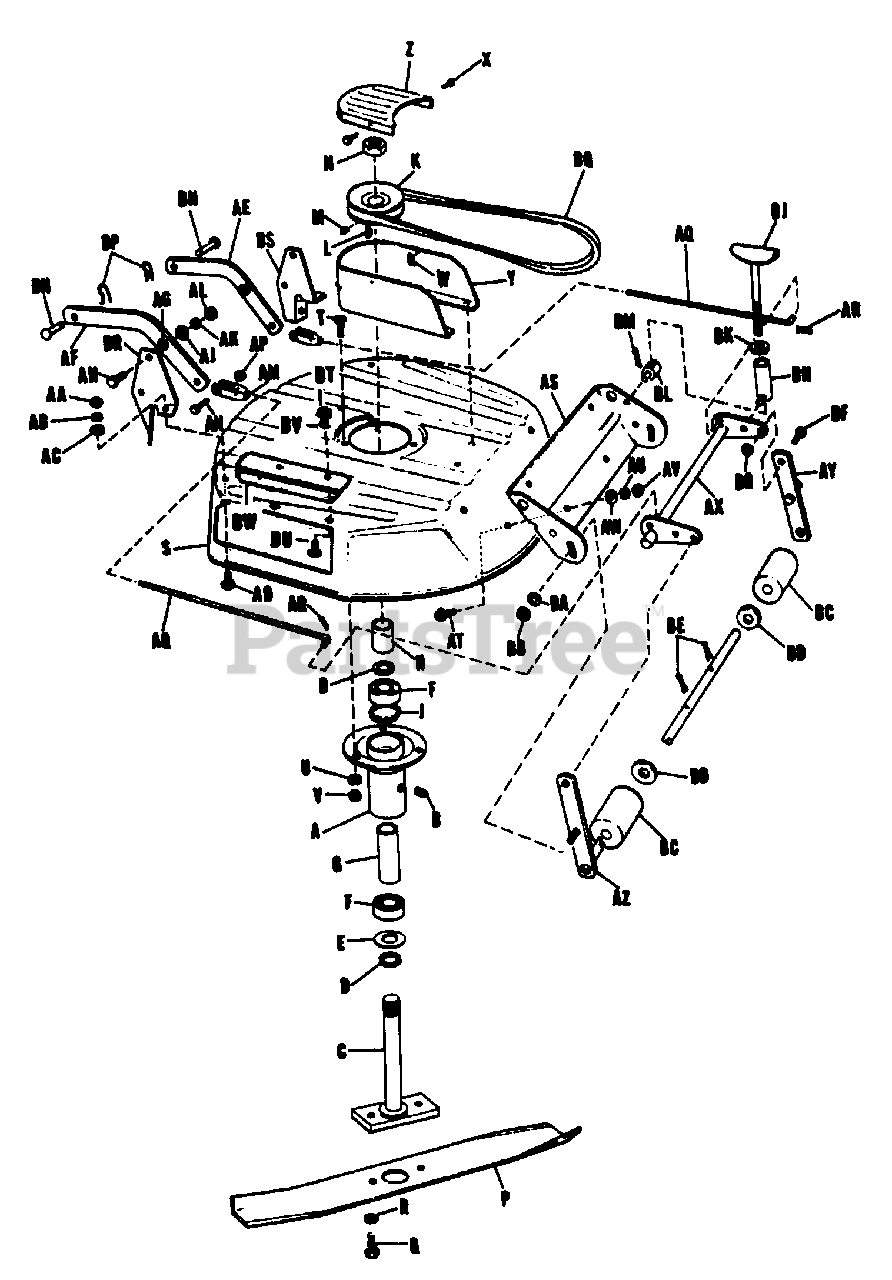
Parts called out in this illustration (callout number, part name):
A	Tube Assembly, Arbor
B	Pipe Plug, 1/8
C	Arbor Assembly
F	Bearing, Ball
J	Backing Ring
L	Woodruff, Key, 3/16 x 5/8 Dia.
M	Set Screw, Socket Head, 5/16-18 NC x 3/8 lg
N	Nut, Hex, Jam, Lock, 3/4-16 NF
P	KnIfe Blade
Q	Capscrew, Hex Hd
R	Washer, Lock, 3/8
T	Capscrew, Hex Hd, 3/8-16 NC x 3/4 lg
U	Washer, Lock, 3/8
V	Nut, Hex, Full, 3/8-16 NC
W	Nut, Tinnerman
X	Screw, Self Tap #10 x 1/2 lg
Y	Pulley Guard
Z	Cover, Guard
AA	Nut, Hex, Full, 3/8-16 NC
AB	Washer, Lock, 3/8
AC	Washer, Plain, 3/8
AD	Bolt, Carriage, 3/8-16 NC x 3/4 lg
AE	Lever, Front, R.H.
AF	Lever, Front, L.H.
AH	Capscrew, Hex Hd, 3/8-16 NC x 1 lg.
AJ	Washer, Plain, 3/8
AK	Washer, Lock, 3/8
AL	Nut, Hex, Full, 3/8-16 NC
AM	Clevis, Adjusting
AN	Capscrew, Hex Hd, 3/8-16 x 1 1/4
AP	Nut, Hex, Full Lock, 3/8-16 NC
AQ	Rod, Height Adjusting
AR	Pin, Cotter, 3/32 x 3/4 lg
AS	Roller Bracket
AT	Capscrew, Hex Hd, 5/16-18 NC x 3/4 lg
AU	Washer, Lock, 5/16
AV	Nut, Hex, Full, 5/16-18 NC
AW	Washer, Plain
AX	Lever Assembly, Rear
AY	Bar Assembly, Roller
AZ	Bar & Shaft Assembly, Roller
BA	Washer, Plain, 3/8
BB	Nut, Hex, Full Lock, 3/8-16 NC
BE	Pin, Cotter, 3/16 x 1 lg
BF	Capscrew, Hex, Hd, 3/8-16 NC x 1 lg
BG	Nut, Hex, Full, 3/8-16 NC
BH	Socket Assembly, Crank
BJ	Screw Assembly, Adjusting
BK	Washer, Plain, 3/8
BM	Pin, Cotter
BP	Clip, Spring
BR	Bracket, Front, L.H.
BS	Bracket, Front R.H.
BT	Nut, Full Hex, 1/4-20
BU	Screw, Hex Hd Cap, 1/4-20 x 1/2"
BV	Washer,Lock
BW	Deflector
